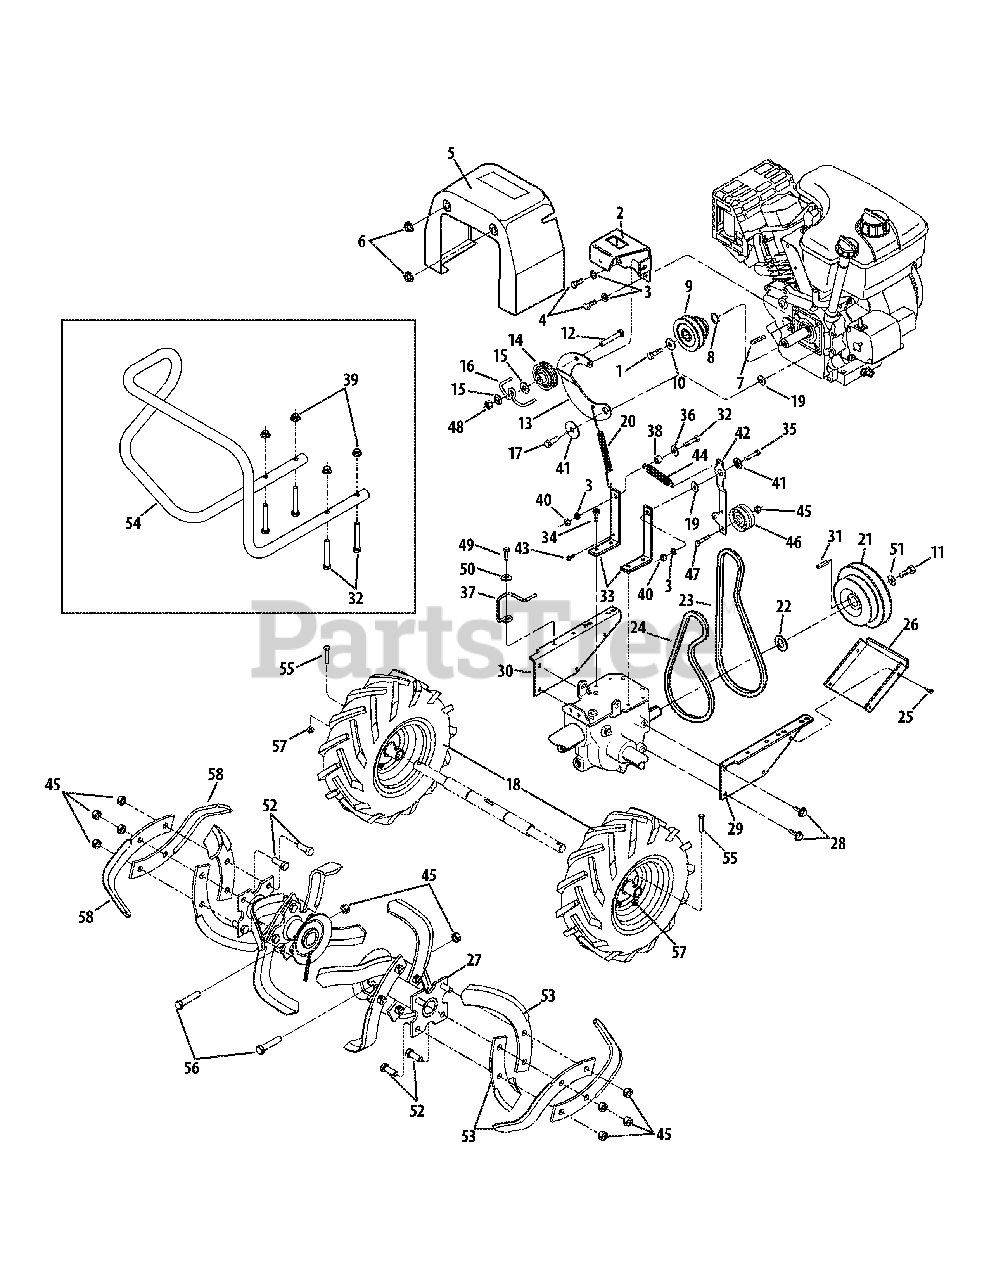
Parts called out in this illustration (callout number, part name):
1	Hex Screw, 3/8-24 x 2.25
1	Screw, 5/16-24 x 1.25
2	Clutch Cable Bracket
3	Lockwasher, 5/16
4	Hex Head Screw, 5/16-24 x 1/2
6	Flange Lock Nut, 5/16-18
7	Key, 3/16-2
7	Key, 3/16 x 1.5
9	Engine Pulley
10	Belle. Washer, .344 x 1.0 x .063
10	Belle. Washer .827 x .331 x .098
11	Hex Head Screw, 5/16-24 x 1-1/8
12	Hex Head Screw, 5/16-18 x 2
13	Reverse Idler Arm
14	Reverse Idler Pulley
15	Flat Washer, 5/16
16	Wire Formed Belt Guide
17	Hex Head Screw, 5/16-24 x 1
18	Wheel Assembly, 13 x 5 x 6
19	Flat Washer, 1-1/8
20	Reverse Return Spring
21	Transmission Pulley
22	Support Washer
23	Reverse Clutch Belt
24	Forward Clutch Belt
25	Self-tapping Screw, #10-32 x 1/2
26	Belts/Pulleys Guard
28	Hex Flange Screw, 5/16-18 x 3/4
29	Engine Support Bracket (left side)
30	Engine Support Bracket (right side)
31	Key, 3/16 x 1.50
32	Hex Head Screw, 5/16-18 x 2-1/4
33	Mounting Bar
34	Hex Flange Screw, 5/16-18 x .75
35	Hex Head Screw, 5/16-18 x 1-1/2
36	Flat Washer, 5/16
37	Belt Guide
38	Pivot Bushing
39	Hex Lock Nut, 5/16-18
40	Hex Nut, 5/16-18
41	Shoulder Washer
43	Self-tapping Screw, #10-24
44	Spring
45	Hex Locknut, 5/16-18
46	Forward Idler Pulley
47	Screw, 3/8-16 x 1-3/4
48	Hex Lock Nut, 5/16-18
49	Screw, 1/4-20 x 3/4
50	Flat Washer, 1/4
51	Belleville Washer, .827 x .331 x .098
52	Hex Head Screw, 3/8-16 x 1
53	Bolo Tine-single (Left)
55	Hex Head Screw, 1/4-20 x 1.5
56	Hex Head Screw, 3/8-16 x 2
57	Flange Hex Locknut, 1/4-20
58	Bolo Tine-single (Right)
